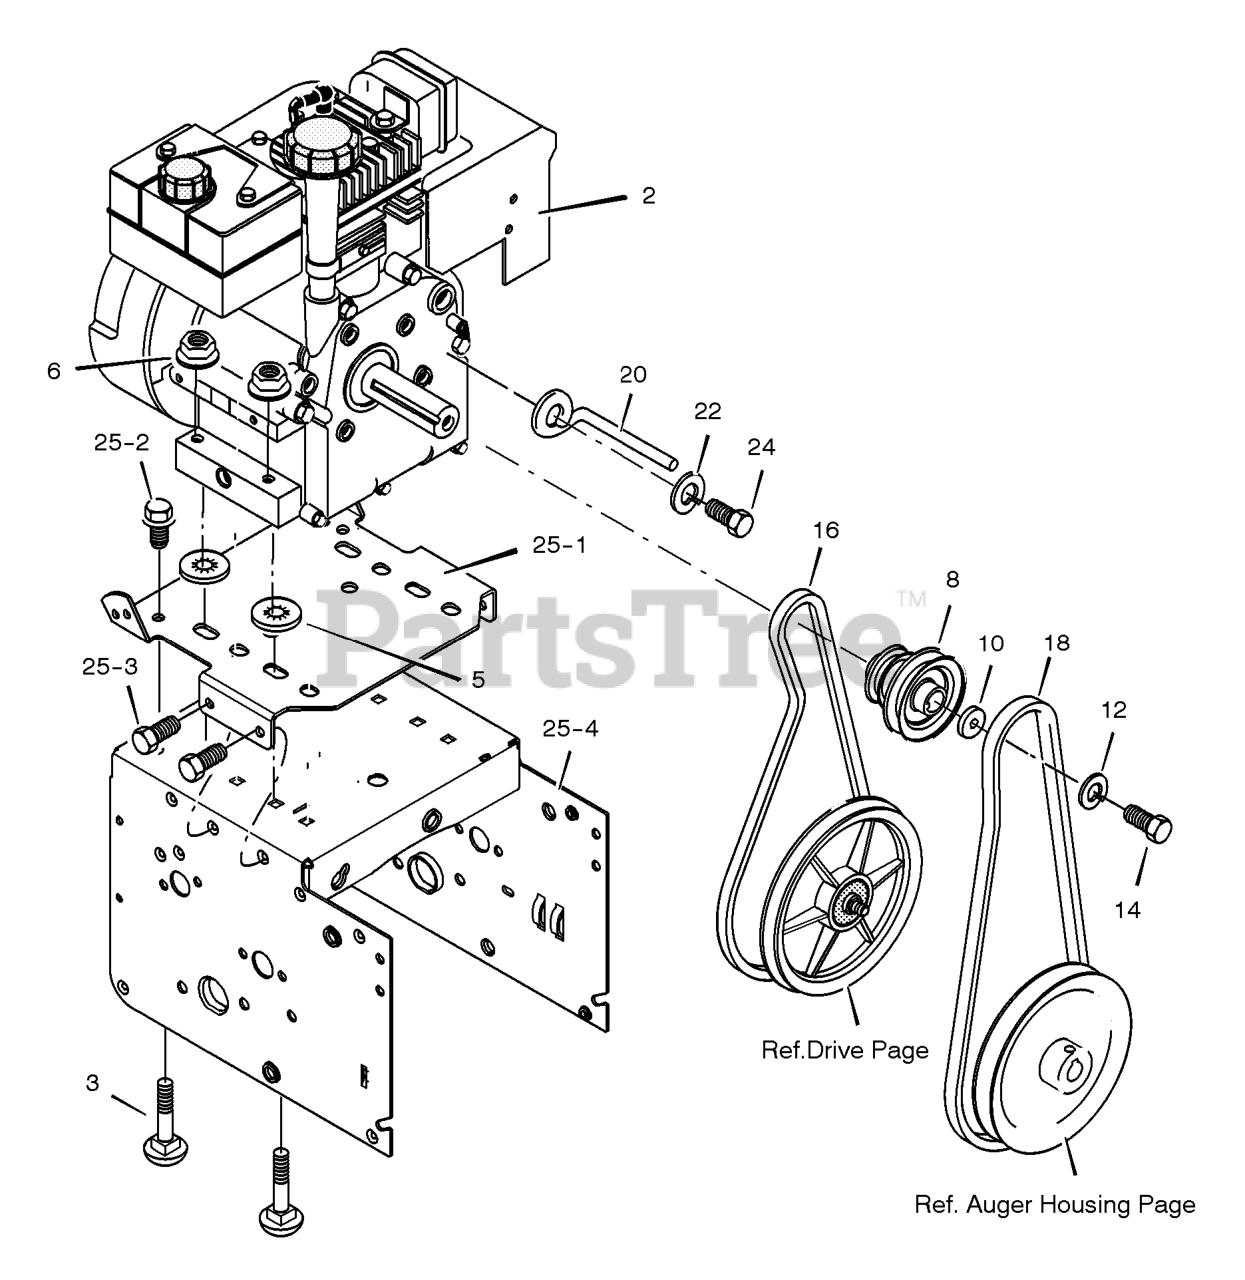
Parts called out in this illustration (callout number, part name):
2	ENGINE
3	BOLT, CARRIAGE 5/16-18
5	RETAINER, PUSH
6	NUT, HEXWDFLLK 5/16-18
8	PULLEY, ENGINE
10	WASHER
12	WASHER .38ID
14	SCREW, 3/8-24 x 1.00
16	BELT, V 3L 33.13LG
18	BELT, V 4L35.6 LG
20	GUIDE, BELT
22	WASHER, SPTLK .31X.58X.08
24	SCREW, 5/16-24 x 0.75
25	FRAME, MOTORBOX
25-1	PLATE, ENGINE MOUNT
25-2	SCREW, TAP 1/4-20 X .63
25-3	SCREW, TAP 5/16-18 X .50
25-4	FRAME, MOTOR BOX
